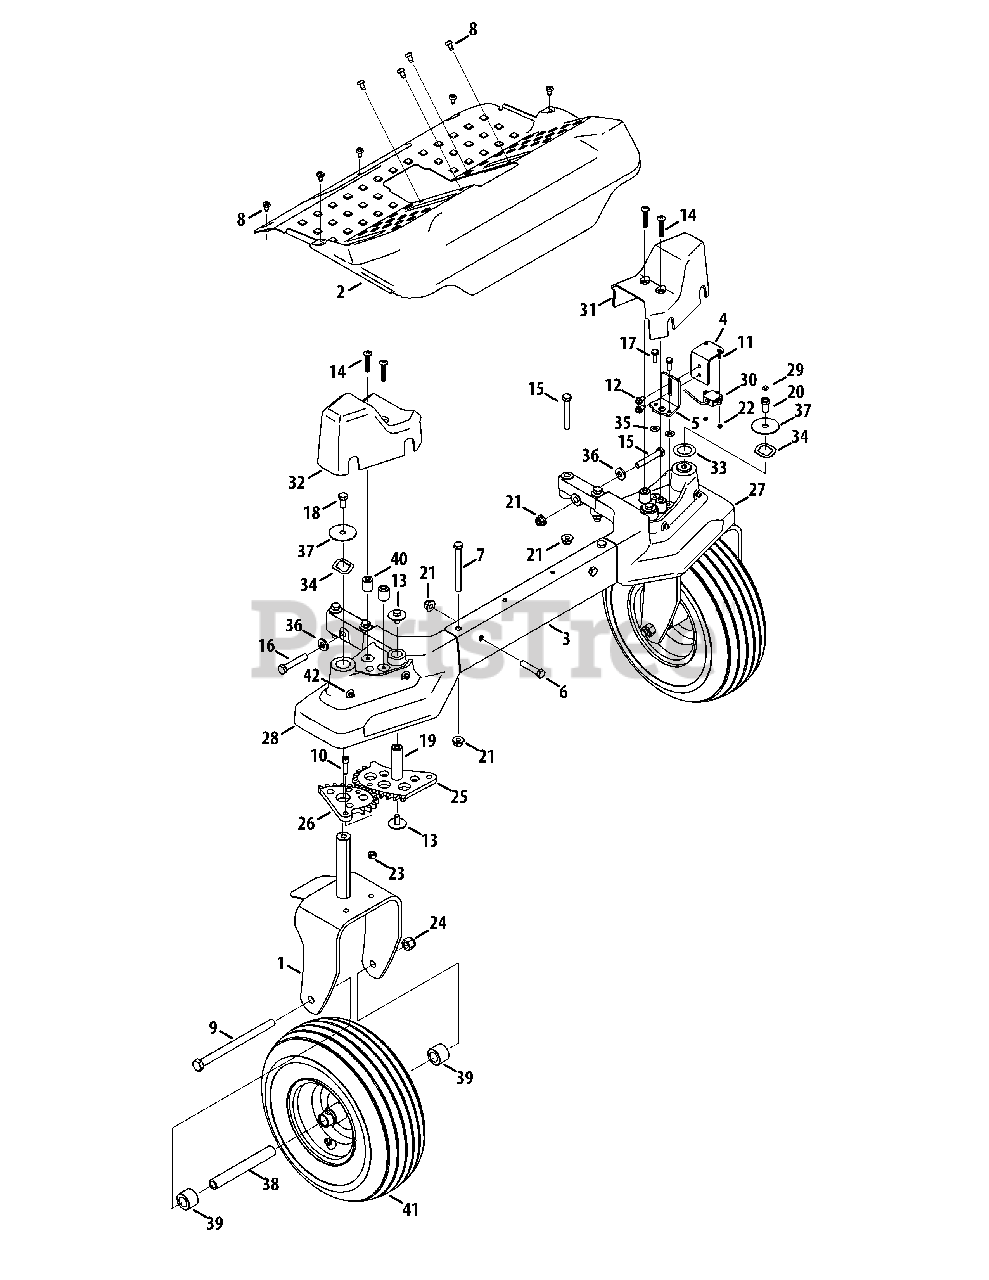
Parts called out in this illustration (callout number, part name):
1	Caster Wheel Bracket
2	Floor Board
4	Steering Sensor Mounting Bracket
5	Sensor Adjustment Mounting Brkt.
6	Hex Cap Screw, 3/8-16 x 1.75
7	Hex Cap Screw, 3/8-16 x 4.0
8	Self Tapping Screw, 1/4-20 x .50
9	Bolt, 1/2-20 x 7.25
10	Socket Head Screw, 5/16-18 x 1.00
11	Screw, #5-40 x .625
12	Hex Washer Screw, 1/4-20 x .500
13	Hex Cap Screw, 5/16-18 x .75
14	Screw, 1/4-20 x 1.50
15	Hex Cap Screw, 3/8-16 x 2.50
16	Hex Cap Screw, 3/8-16, 2.25
17	Hex Cap Screw, 1/4-20 x 0.75
18	Hex Screw, 3/8-16 x .75
19	Pivot Gear Steering Shaft
21	Flange Lock Nut, 3/8-16
22	Hex Lock Nut, #5-40
23	Hex Lock Nut, 5/16-18
24	Hex Lock Nut, 1/2-20
25	12-Tooth Variable gear
26	13-Tooth Variable gear
27	Pivot Axle, LH
28	Pivot Axle, RH
29	Magnet-Rotary Sens
30	Sensor-Rotary
31	Axle Cover, LH
32	Axle Cover, RH
33	Flat Washer, 1.006 x 1.56 x .020
34	Wave Washer, 1.5 x 1.0 x .029
35	Flat Washer, .25 x .63 x .052
36	Flat Washer, .406 x .875 x .105
37	Flat Washer, .406 x 1.92 x .060
38	Spacer, .51 ID x .75 OD x 5.825
39	Hub, .76 x 1.23 x .92 LG
40	Shoulder Spacer, .28 x .75 x .837
41	Wheel Assembly, 13 x 5-6
42	Grease Fitting
